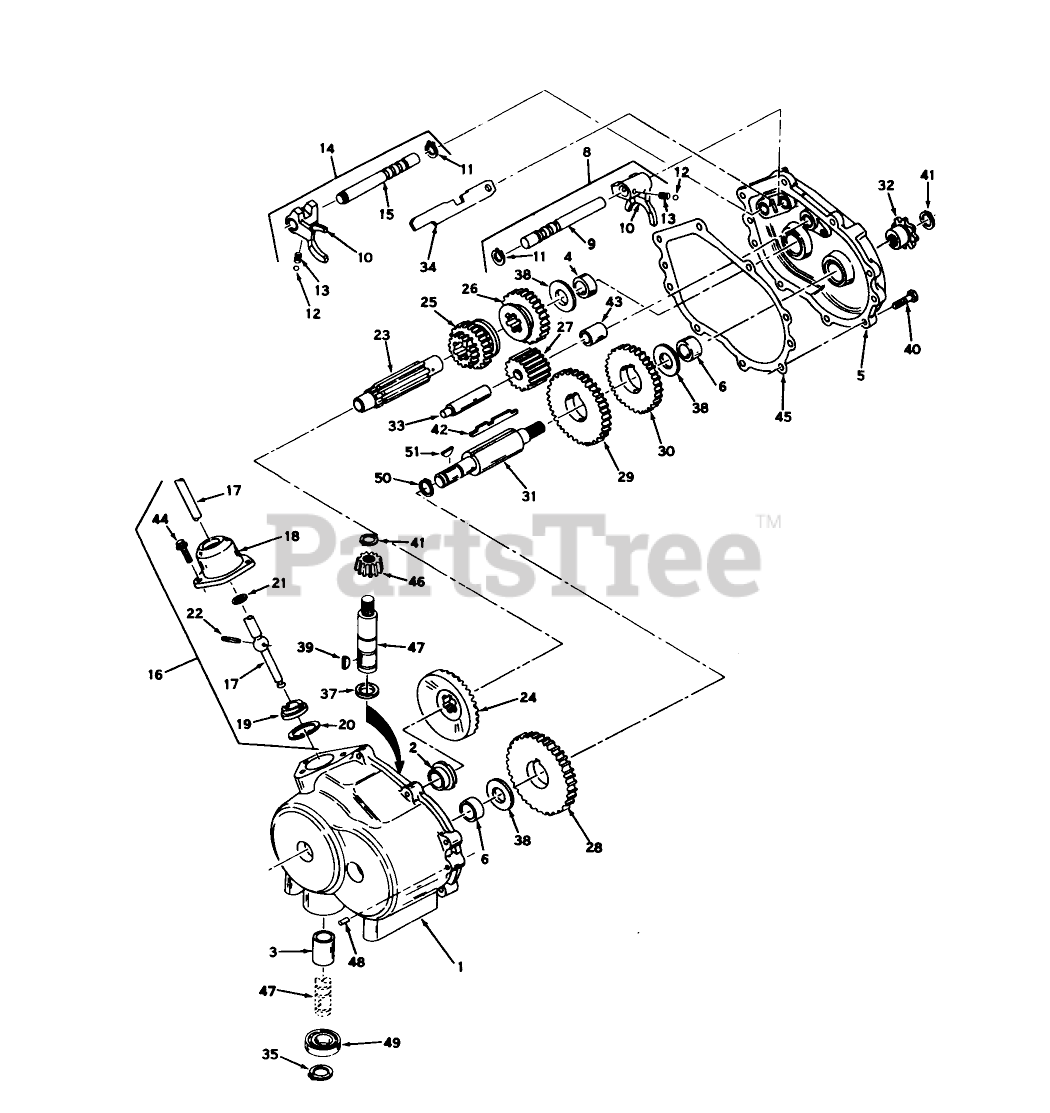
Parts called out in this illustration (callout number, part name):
1	Case Assy., Transmission (Incl. Nos. 2, 3 6)
2	Bearing, Bronze
3	Bearing, Bronze
4	Bearing, Bronze
5	Cover Assembly, Transmission (Incl. Nos. 4 6)
6	Bushing, Bronze
8	Shift Rod Assy (1st and Rev.)(Incl. Nos. 26 thru 30)
9	Shift Rod
10	Shift Fork
11	Ring-Snap
12	Piston ASM
13	Spring
14	Rod Assy., Shift (Incl. Nos. 10 thru 13 15)
15	Rod, Shift
16	Lever Housing Assy., Shift (Incl. Nos. 17 thru 22)
17	Lever, Shift
18	Shift Lever Housing
19	Keeper-Shift Lever
20	Ring-Snap
21	O Ring
22	Roll Pin
23	Shaft, Shifter
24	Gear, Bevel (33 teeth)
25	Gear, Shift 1st 2nd)
26	Gear, Shift 3rd Rev.)
27	Idler, Reverse
28	Gear (39 teeth)
29	Gear (34 teeth)
30	Gear (30 teeth)
31	Shaft, Output
32	Sprocket (8Teeth)
33	Shaft, Reverse Idler
34	Stop, Shifter
35	Ring-Snap
37	Bearing, Thrust
38	Washer
39	Key, Woodruff
40	Screw-Thread Forming
41	Ring-Retainer
42	Key, Countershaft
43	Reverse Idler Spacer
44	Screw
45	Gasket, Transmission
46	Pinion, Input
47	Shaft, Input
48	Dowel Pin
49	Bearing-Ball
50	Snap Ring
51	Kev. Woodruff
